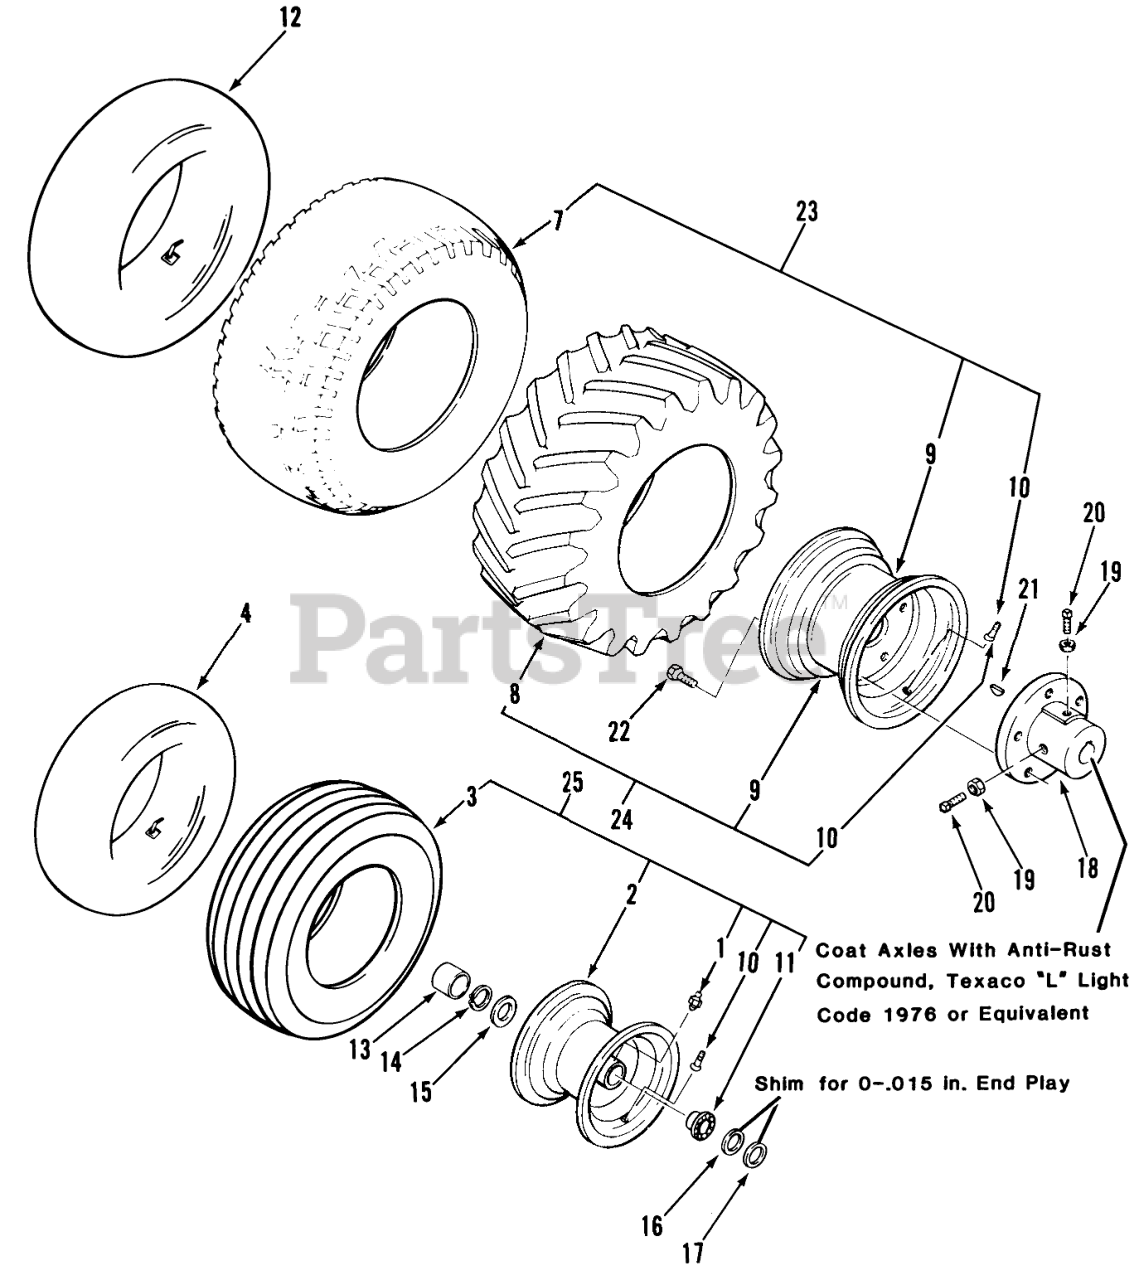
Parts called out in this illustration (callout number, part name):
1	Zerk
2	Front Wheel (includes Item 1,10,11)
3	Front Tire 16 x 6.50-8
4	TUBE-INNER
7	Rear Tire 23 x 10.50-12 GT-1800 Only
7	Tire
7	TIRE 9.50 X 12
8	Tire-Cleat, Rear
9	WHEEL RIM
9	Rear Wheel GT-1100, GT-1600 Only
10	VALVE
11	Bearing
12	Rear Tube
12	TUBE-INNER
13	HUB CAP-FLAT BLACK
14	Snap Ring
15	WASHER-WHEEL
16	WASHER
17	WASHER-SHIM
18	Hub Rear
18	Hub-Rear
19	Nut
20	Screw-Set
21	KEY-WOODRUFF
21	WOODRUFF KEY
22	Lug Nut
23	Rear Wheel and Tire Assy Turf GT-1848 Only
23	Rear Wheel and Tire Assy Turf GT-1142 Only
23	Rear Wheel and Tire Assy Turf GT-1642 Only
24	Right Rear Wheel and Tire Assy-Cleat
24	Left Rear Wheel and Tire Assy-Cleat
25	Front Wheel and Tire Assy
